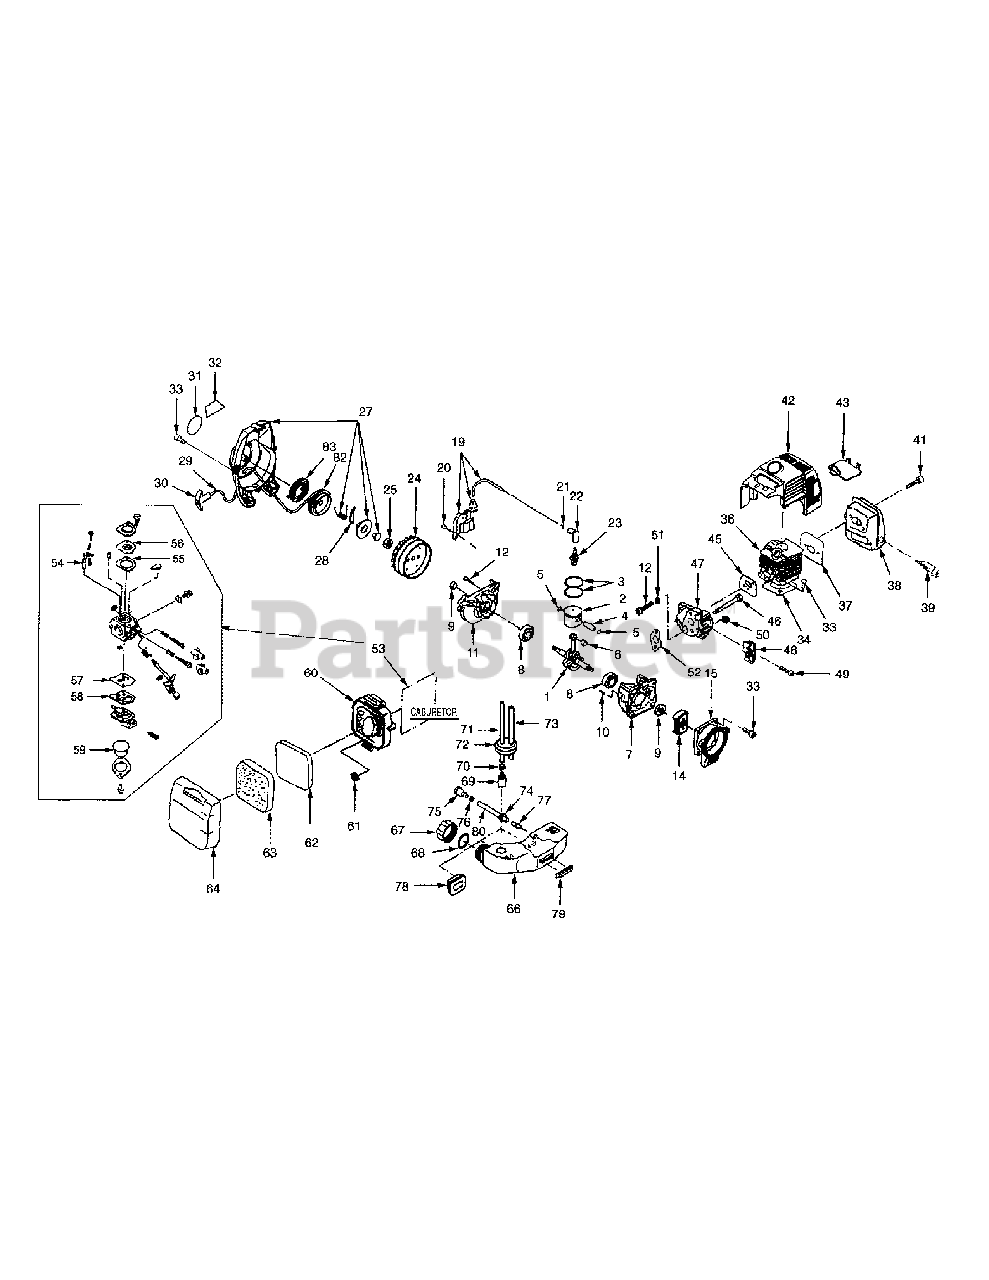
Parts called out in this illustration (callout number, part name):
2	Piston Assembly
3	Ring, Piston
5	Clip, Piston Pin
6	Bearing, Needle
7	Crankcase Assembly
8	Bearing, Ball, 6201
11	Crankcase Assembly
14	Clutch Assembly
19	Coil Assembly, Ignition
23	Spark Plug
24	Flywheel, Magneto
27	Housing, Assembly, Blower
29	Rope, Starter
30	Knob, Starter
32	Caution Plate
37	Gasket, Muffler
42	Cowling, Cylinder
43	Baffle Plate
45	Gasket, Insulator
51	Washer
52	Gasket
53	Carburetor Assembly
54	Valve, Float
56	Diaphragm, Metering
57	Diaphragm, Pump
60	Case, Air Silencer
62	Element "B", Air Filter
63	Element "A", Air Filter
67	Cap Assembly, Fuel Tank
69	Filter, Fuel
71	Hose
73	Hose
75	Valve, Reversing
79	Rubber
83	Spring, Spiral
